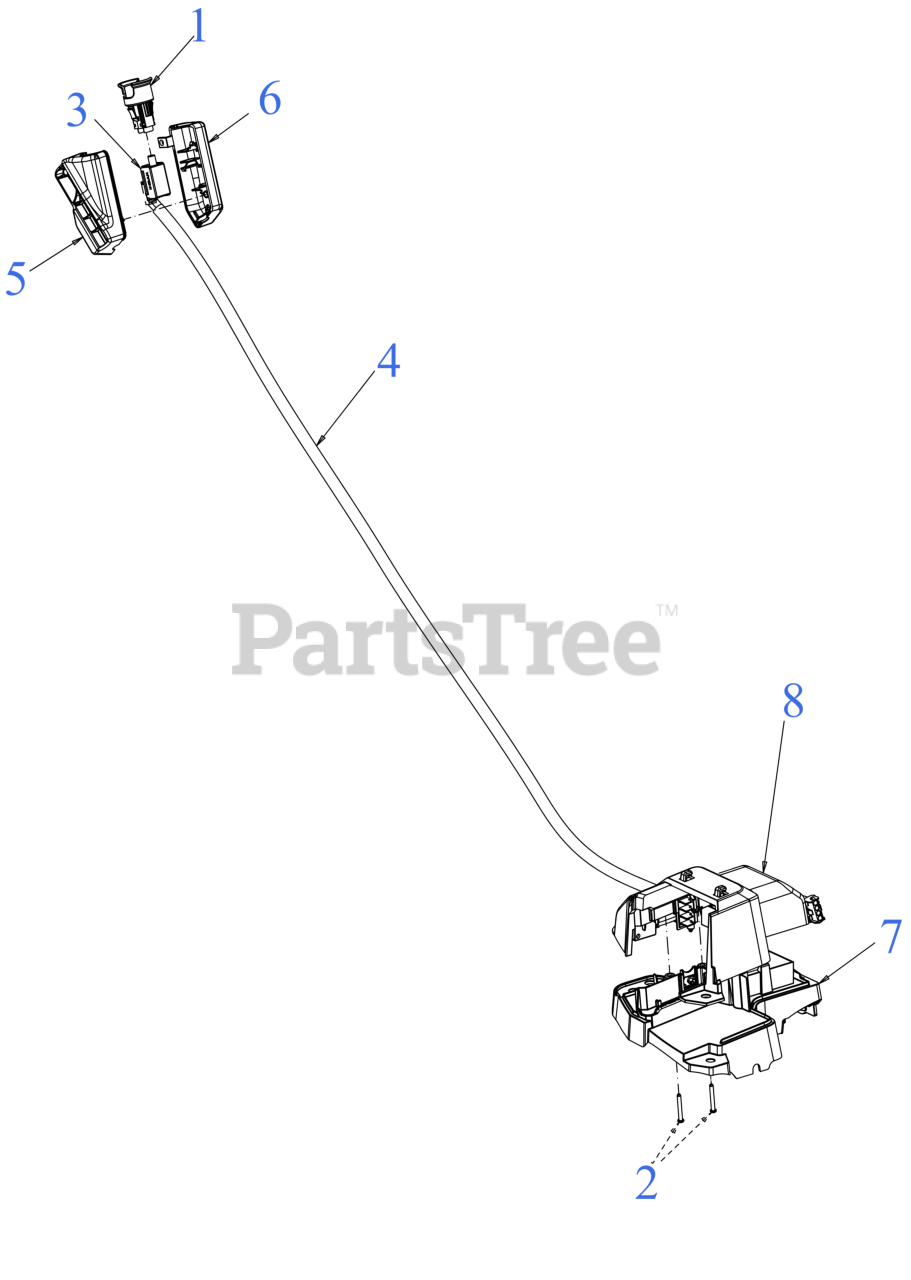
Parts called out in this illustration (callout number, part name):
1	PUSH KEY SWITCH ASSEMBLY
2	SCREW #8-18 x 1.250
3	PLUNGER SWITCH 20A
4	WIRING HARNESS LI-ION ESTART
5	PUSH START HOUSING (RH)
6	PUSH START HOUSING (LH)
7	BATTERY HOUSING (BOTTOM)
8	BATTERY HOUSING (TOP)
